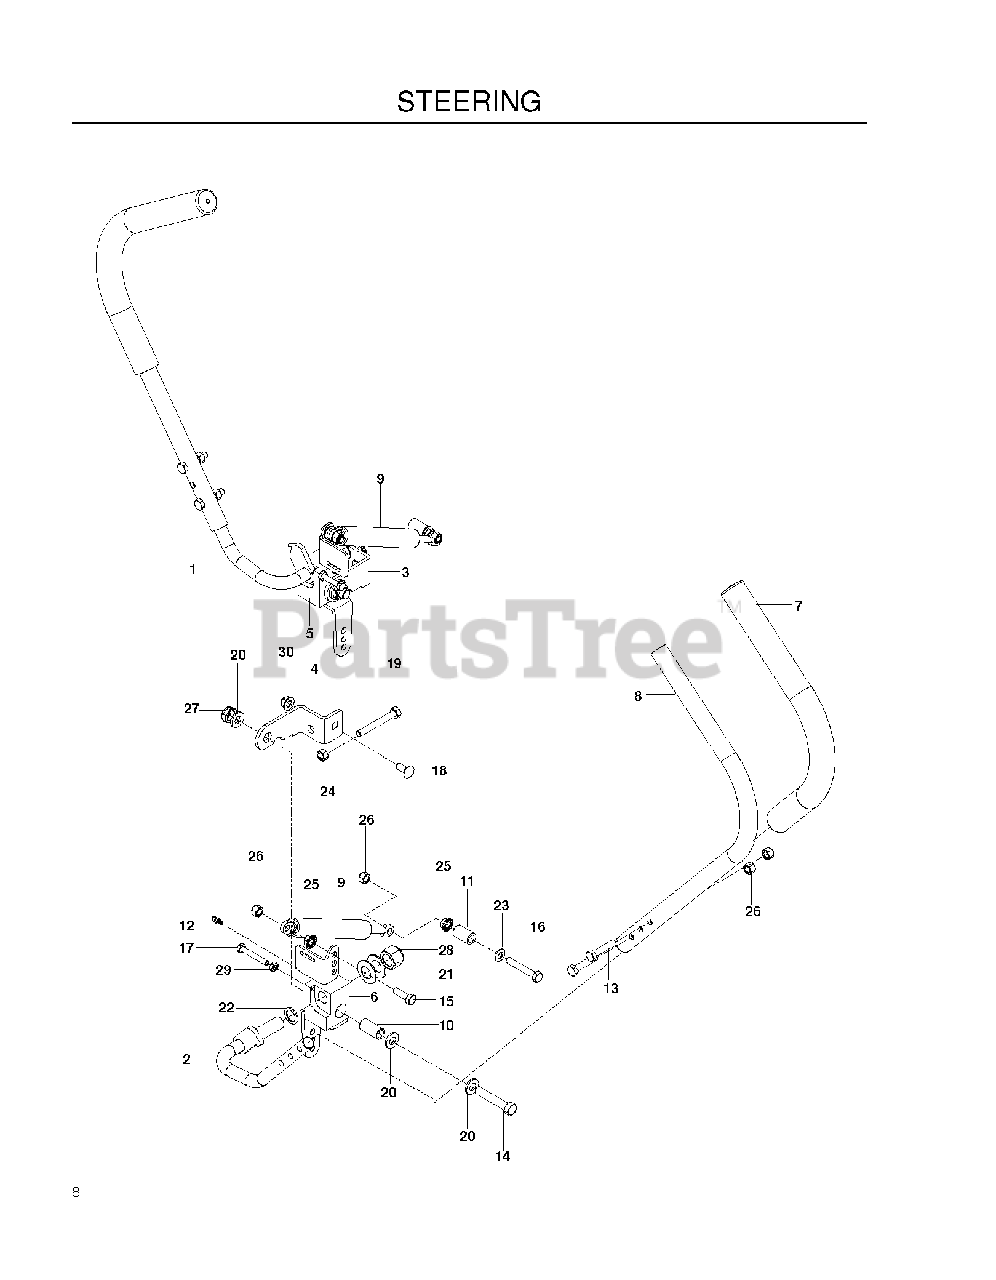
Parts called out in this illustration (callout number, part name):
1	LEVER.PLATED.RH
2	LEVER PLATED LH
3	FORWARD STOP RH
4	FORWARD STOP LH
5	PIVOT RH (PLATED)
6	PIVOT LH (PLATED)
8	LEVER UPPER
9	DAMPENER, DUAL ACTION
12	ZERK, 3/16, DRIVE IN
13	CAPSCREW 5/16 X 1/1/2 HEX HEAD
14	HCS 1/2C X 2 3/4
15	HCS 5/16C X 1
16	HCS 5/16-18X2
17	BOLT 1/4C X 1 3/4
18	BOLT 5/16C X 3/4" CARRIAGE
19	HCS 5/16-18 X 2 1/2 TPBLT
20	WASHER 1/2" FLAT
21	WASH 5/8 BEVELED DISC SPRING
22	WASHER-.626IDX.056TK
23	FLAT WASHER 5/16 SAE
24	NUT 5/16C HEX
25	NUT 5/16C WHIZ
26	NUT 5/16 NYLOC
27	NUT 1/2-13 HEX JM NYL
28	NUT 5/8-11 NYLOC
29	NUT 1/4-20 JAM
30	5/16-18 NYLOC FLANGE NUT
